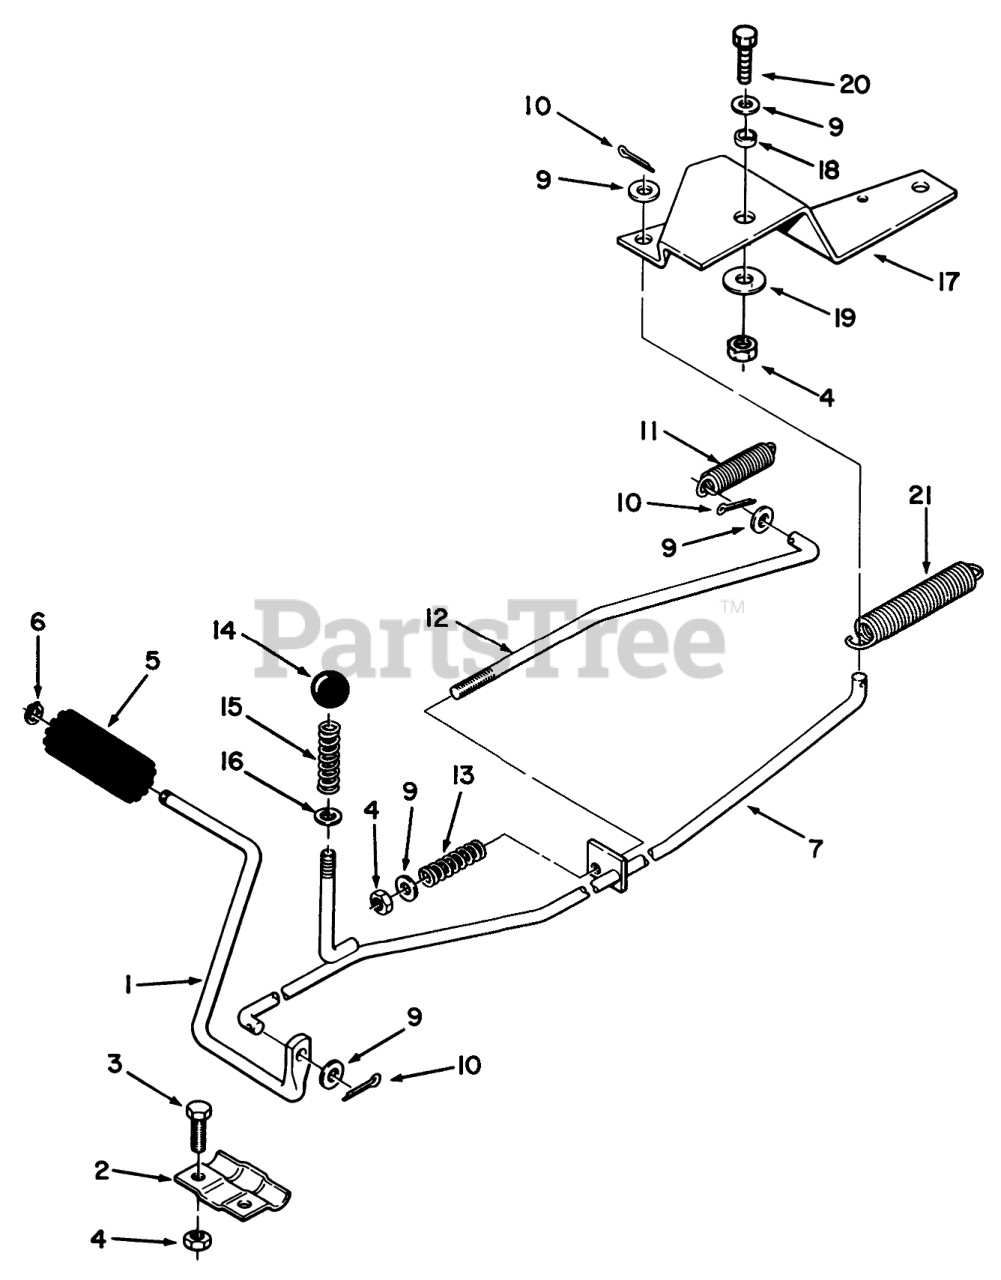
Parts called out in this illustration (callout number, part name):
1	ROD-BRAKE PEDAL R
2	SPINDAL SUPPORT R
3	SCREW-HH
4	NUT-LOCK, NI
5	PAD-CLUTCH/BRKE PDL
6	RING-EXT GRIP
7	ASSY CLUTCH ROD
9	WASHER-FLAT
10	PIN-COTTER
11	SPRING-EXTENSION
12	ROD BRAKE
13	SPRING-COMPRESSION
14	KNOB
15	SPRING
16	WASHER
17	LEVER CLUTCH R
18	SPACER
19	WASHER
20	SCREW-HH
21	SPRING EXTENSION
